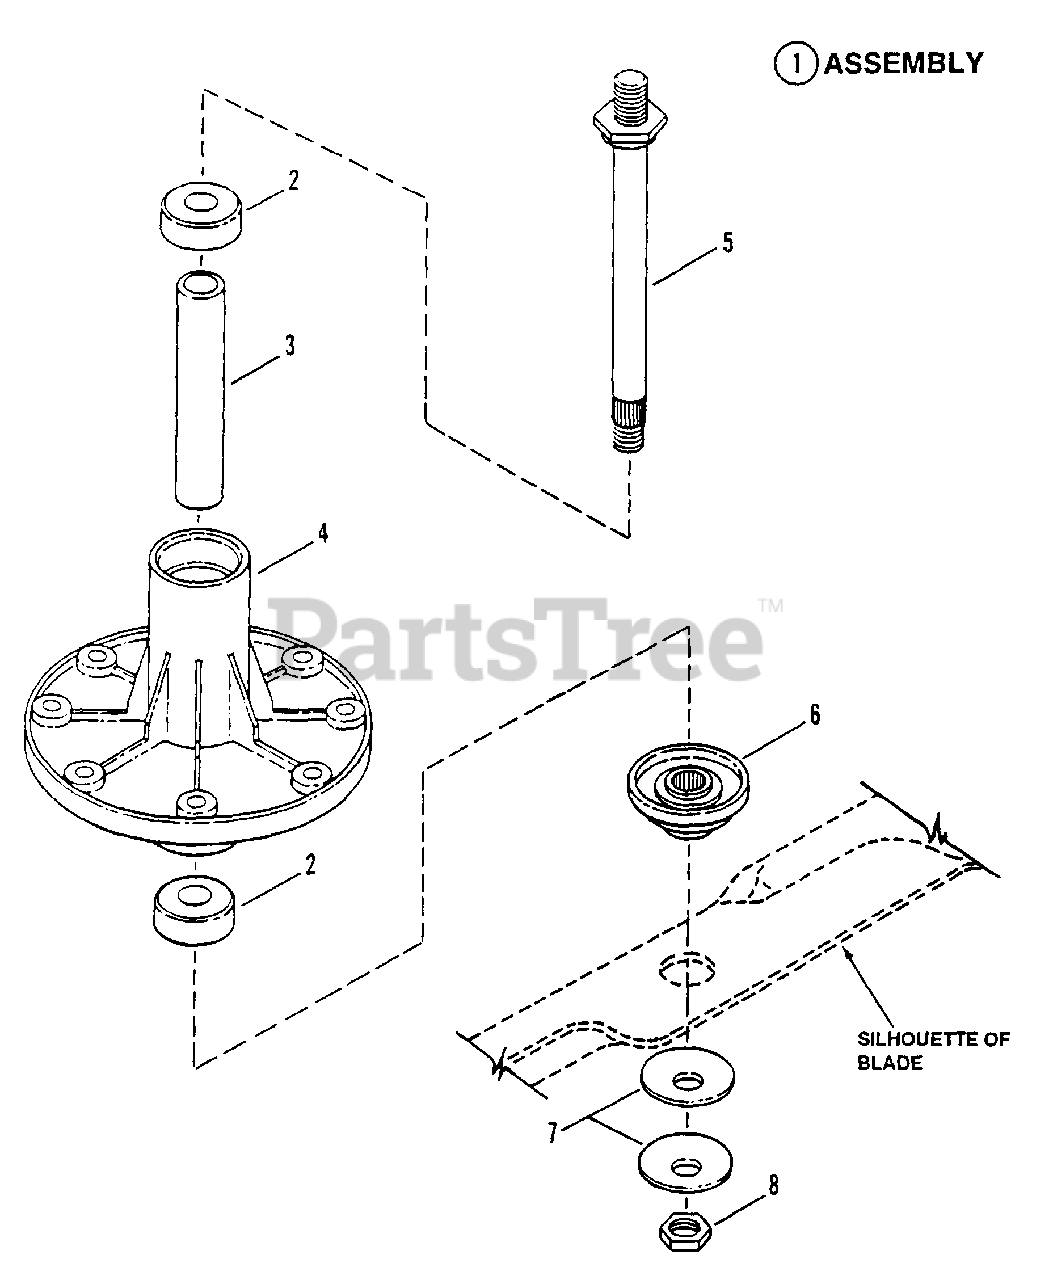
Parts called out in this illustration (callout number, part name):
1	ASSEMBLY, Spindle Housing, 38" Cutting Deck
2	BEARING, Spindle
3	SPACER, Spindle Housing
4	HOUSING, Spindle
5	SPINDLE, (6.899")
6	SPACER, Blade
7	WASHER, Belleville, 19/32" I.D., 1 3/4" O.D.
8	NUT, 9/16-18 Hex Jam
